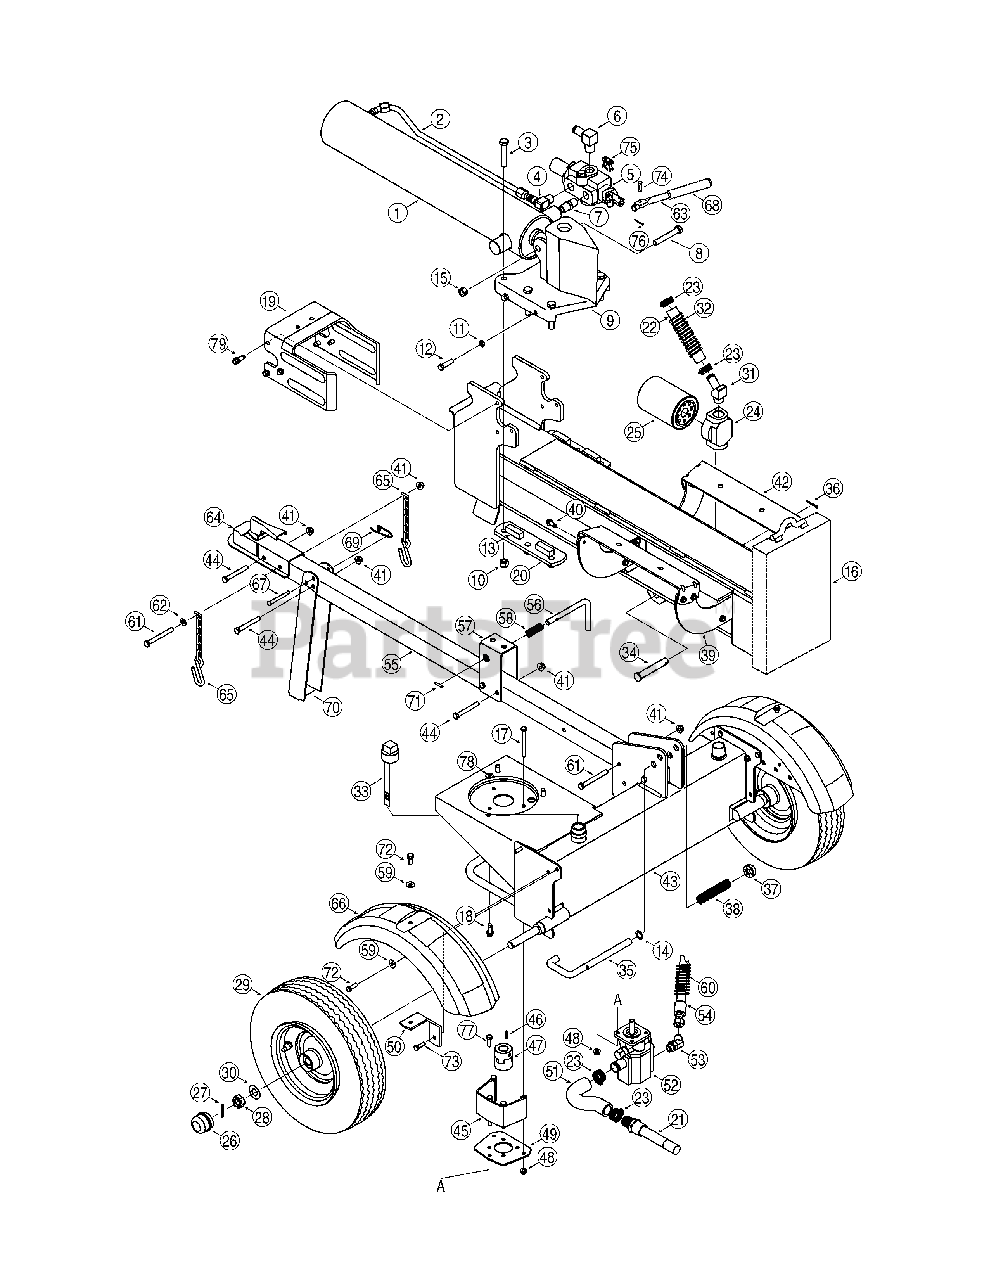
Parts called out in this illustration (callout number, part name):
1	Hydraulic Cylinder
2	Hydraulic Tube
3	Hex Cap Screw 1/2-20 x 2.75
4	90 Degree Solid Adapter
5	Control Valve
6	Return Elbow
7	Nipple Pipe 1/2-14
8	Hex Cap Screw 1/2-13 x 3.25
9	Wedge Assembly
10	Hex Lock Nut, 1/2-20
11	Hex Jam Nut 3/8-24
12	Hex Cap Screw 3/8-24 x 1.5
14	Flat Washer.635 x.93 x.06
15	Hex Lock Nut 1/2-13
16	Beam Assembly
17	Hex Screw, 5/16-18 x 3.25
18	Hex Washer Screw 3/8-16 x 1.250
19	Dislodger Bracket
20	Back Plate
21	Inlet Filter
22	Return Hose 3/4" ID x 44" Lg.
23	Hose Clamp 5/8"
24	Filter Housing
25	Oil Filter
26	Hub Cap
27	Cotter Pin
28	Slotted Nut 3/4-16
29	Wheel Assembly
30	Flat Washer.760 ID x.500 OD
31	Adapter 3/4-14
32	Hose Guard
33	Vented Dipstick
34	Clevis Pin
35	Lock Rod
36	Cotter Pin
37	Push Cap
38	Compression Spring
39	Log Tray Bracket
40	Hex Washer Screw, 5/16-18 x .750
41	Flange Lock Nut, 3/8-16
43	Frame Assembly
44	Hex Bolt 3/8-16 x 3
45	Coupling Shield
46	Square Key 3/16" x.75
47	Screw, 1/4-20 x .38
47	Coupling, .500
47	Coupling, .875
47	Spider Coupling
48	Flange Lock Nut, 5/16-18
49	Rear Coupling Support Bracket
50	Fender Mounting Bracket
52	Gear Pump
53	45 Degree Elbow Fitting
54	High Pressure Hydraulic Hose
55	Tongue Assembly
56	Latch Rod
58	Compression Spring
59	Flat Washer
60	Hose Guard
61	Hex Cap Screw, 3/8-16 x 3.50
62	Flat Washer,.375 x.738 x.063
63	Hydraulic Valve Control
64	Hitch Coupling Assembly
66	Fender
67	Clevis Pin
69	Spring Pin
70	Jack Stand
71	Spiral Pin
72	TT Screw, 5/16-18 x 0.875"
73	TT Screw, 5/16-18 x 1.00
74	Clevis Pin
75	Valve Handle Link
76	Cotter Pin
77	Hex Screw, 5/16-18 x 1.00
78	Flat Washer, .407 x .812 x .135
79	Hex Washer Screw, 3/8-16 x 1.000
